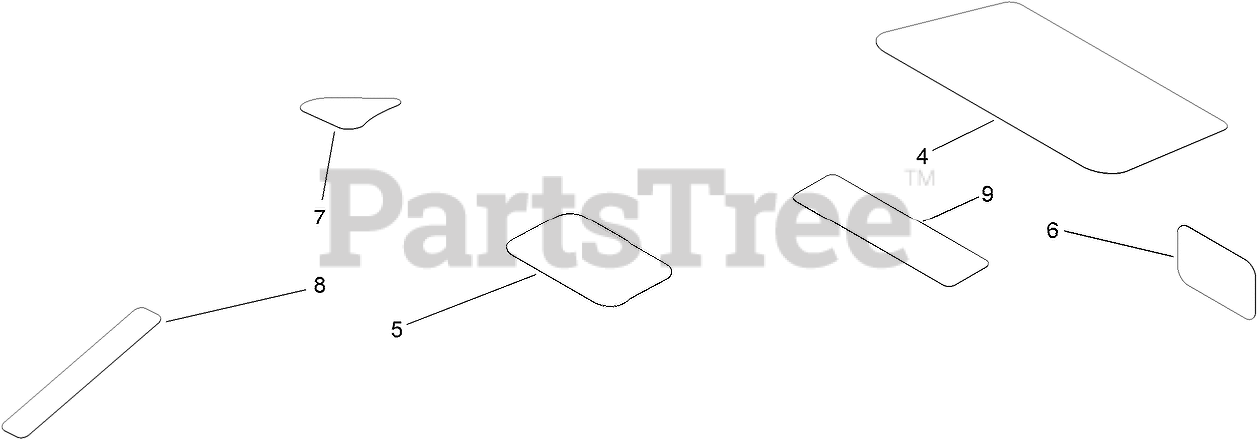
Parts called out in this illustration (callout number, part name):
4	DECAL-ENGINE
6	PLACARD-INTAKE
7	DECAL-DRAIN, OIL
8	DECAL-SHUTDOWN
9	DECAL-BUCKET
